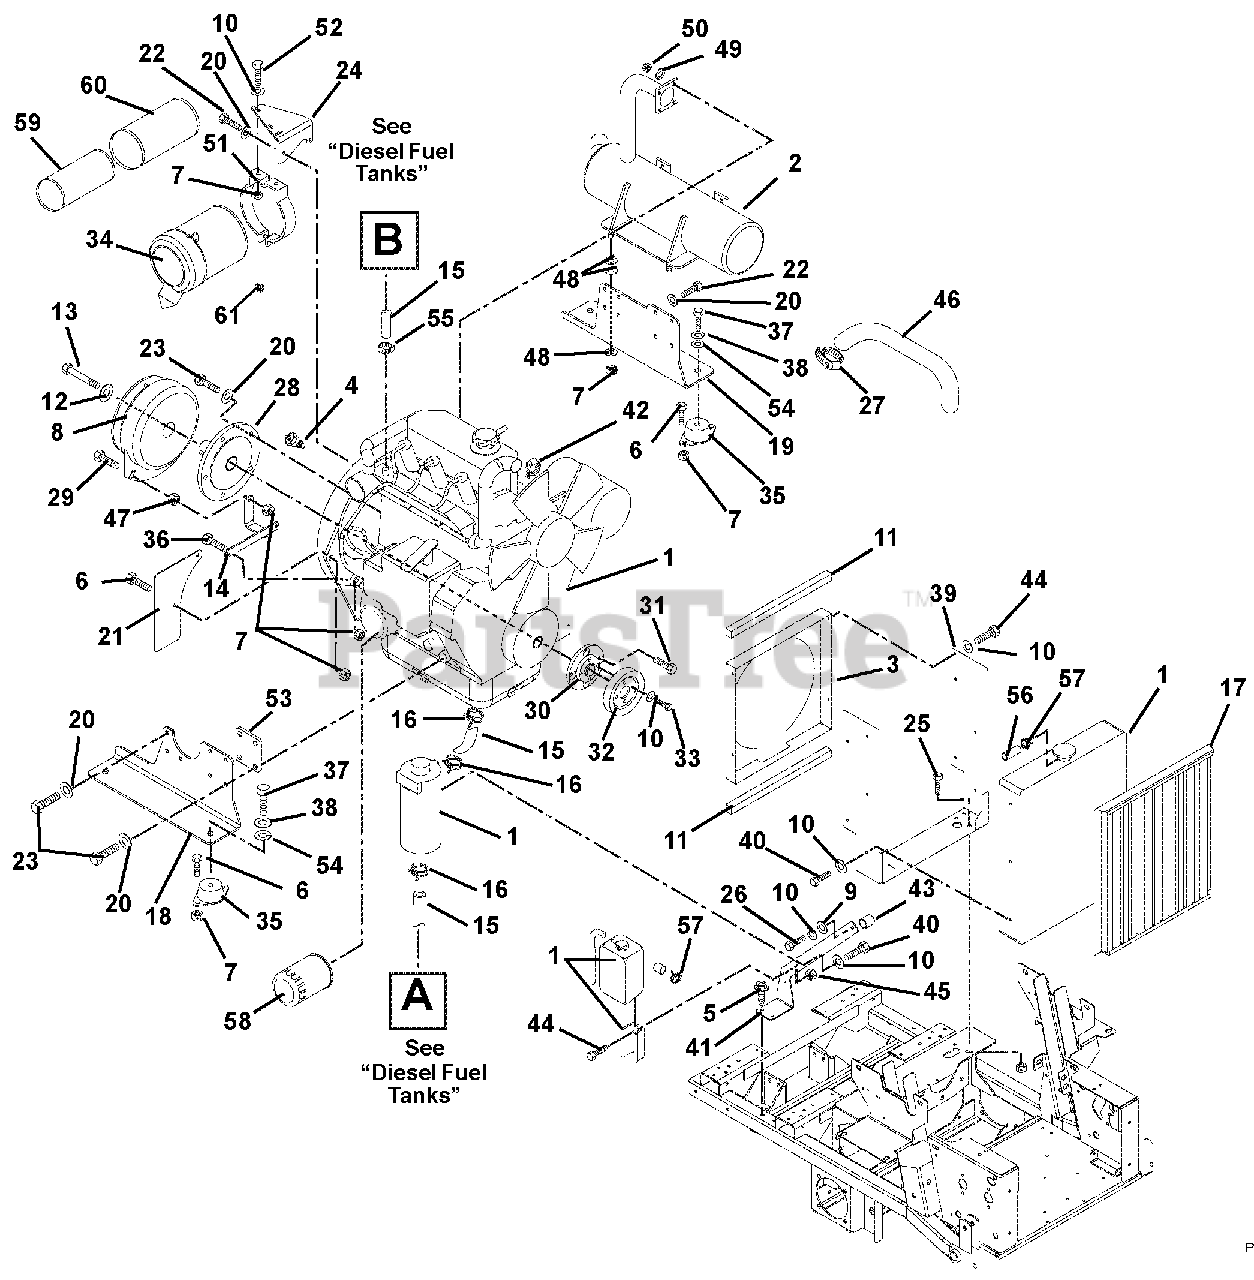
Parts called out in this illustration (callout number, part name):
1	ENGINE, 27HP DIESEL (DAIHATSU)
2	MUFFLER
3	WMT, RADIATOR SHROUD
4	SENDER, TEMPERATURE
5	@SCR-TAP .38-16X.75 HWH TR YWZ
6	@BLT-HEX .31-18X.75 GR5 YWZC
7	@NUT-LK-TOP-FLG .31-18 YWZC
8	CLUTCH, ELE-W/HI TEMP GREASE
9	@WSHR-FL-STL.281X.62X.065 YWZC
10	@WSHR-LK .25X.062 REG YWZC
11	SEAL, TRIM-LOK BULK .06 BBL 1'
12	@WSHR-LK .44X.109 REG YWZC
13	BLT-HEX .44-20X2.50 GR5 YWZC
14	STABILIZER, CLUTCH
15	HOSE,5/16 ID
16	CLAMP, HOSE WIRE .520/.550
17	SCREEN, RADIATOR (DIESEL)
18	MOUNT, ENGINE RH (DIESEL)
19	MOUNT, ENGINE LH (DIESEL)
20	@WSHR-LK .31X.078 REG YWZC
21	GUARD, FLYWHEEL
22	@BLT-HEX M8-1.25X20 YWZC
23	BLT, HEX M8-1.25X25 GR8.8YWZC
24	BRKT, AIR CLEANER - BLACK
25	@BLT-HEX .38-16X1.00 GR5 YWZC
26	@BLT-HEX M6-1.00X45 YWZC
27	CLAMP, HOSE #32 (1.56/2.50)
28	SHAFT, STUB (BRIGGS-DIESEL)
29	@BLT-HEX .31-18X1.50 GR5 YWZC
30	ADAPTER, SHEAVE (DIESEL)
31	BLT, FSCHS M8-1.25X25
32	SHEAVE, POLY V 1.000 X 3.25
33	@BLT-HEX .25-20X.75 GR5 YWZC
34	AIR CLEANER ASSEMBLY
35	MOUNT, ENGINE, VIBRATION ISO
36	@BLT-HEX .31-18X1.00 GR5 YWZC
37	BLT-HEX .50-20X1.00 GR5 YWZC
38	@WSHR-LK .50X.125 REG YWZC
39	WMT, RADIATOR MOUNTING BKRT
40	@BLT-HEX M6-1X16 YWZC
41	BRKT, OVERFLOW MOUNTING - BLK
42	CLAMP-HOSE 1.50X.81X1.42
43	SPACER .328 X .76 X 1.01
44	@BLT-HEX .25-20X.75 GR5 YWZC
45	@NUT-LK-TOP-FLG .25-20 YWZC
46	HOSE, AIR CLEANER
47	@NUT-HEX .31-18 YWZC
48	@WSHR-FL-STL.38X.875X.083 YWZC
49	@WSHR-LK .31X.078 REG YWZC
50	NUT-HEX M8-1.25 YWZC
51	BRACKET, AIR CLEANER MOUNT
52	@WSHR-FL-STL.38X.875X.083 YWZC
53	SPACER, ENGINE MTG (DIESEL)
54	@WSHR-FL-STL.531X1.06X.095YWZC
55	CLAMP, HOSE, IDEAL 6202 SIZE 4
56	GAS LINE-BULK 1/4" I.D.
57	CLAMP-HOSE WIRE .490/.510X.116
58	FILTER, OIL
59	ELEMENT, INNER SAFETY
60	ELEMENT, OUTER PRIMARY
61	FTG,LUBE 45 DEG
NS	KIT,BRAKE POLE MODULE REPLACE
